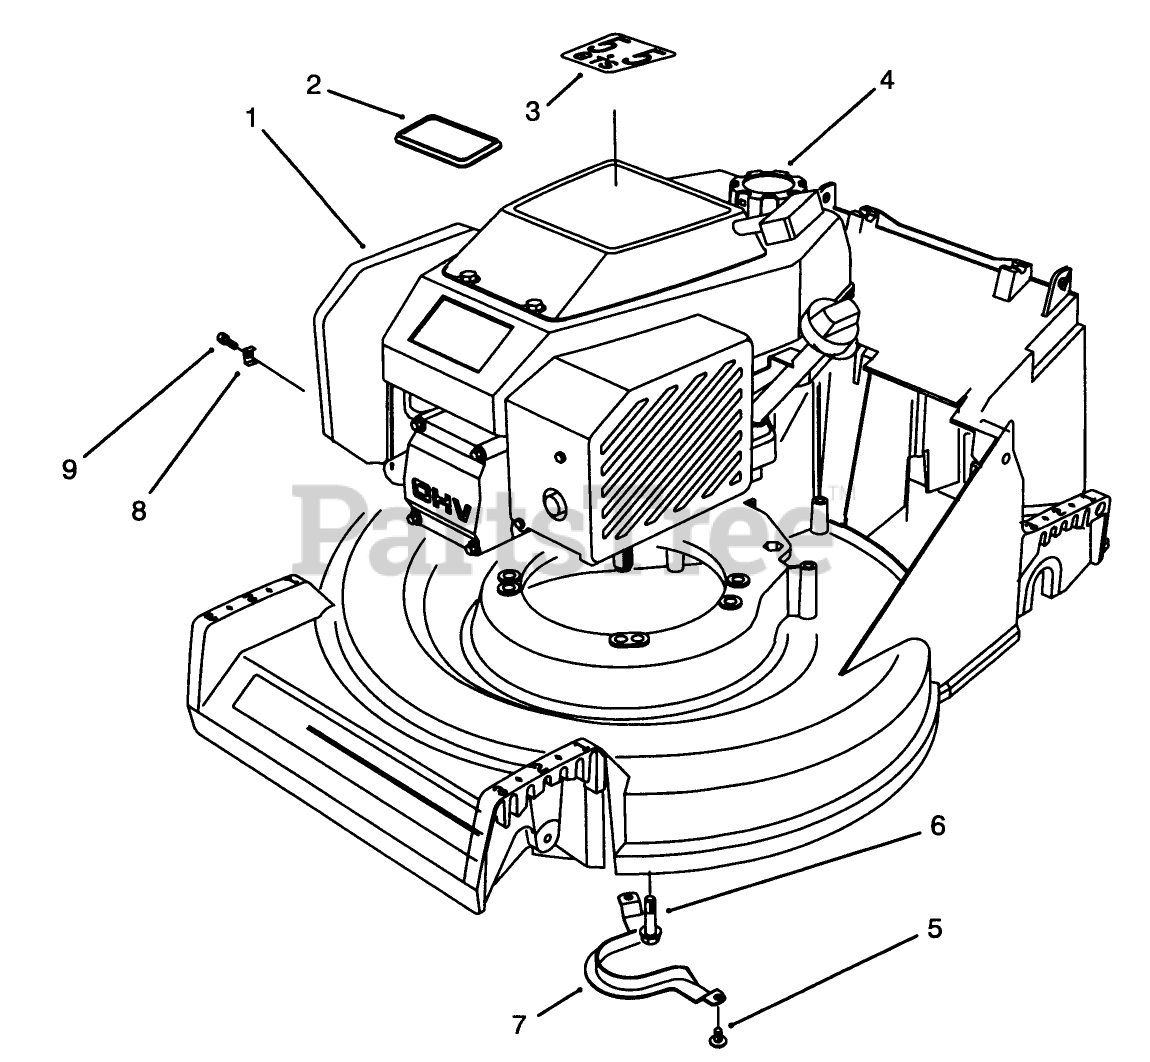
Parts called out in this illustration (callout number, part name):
1	Engine
2	PLATE-LOGO
3	DECAL - ENGINE
4	GAS CAP ASM
5	SCREW-HWHTF
6	SCREW-HWH
7	Guide-Belt
8	CLAMP-CASING
9	CLAMP SCREW F/W ENGINE
